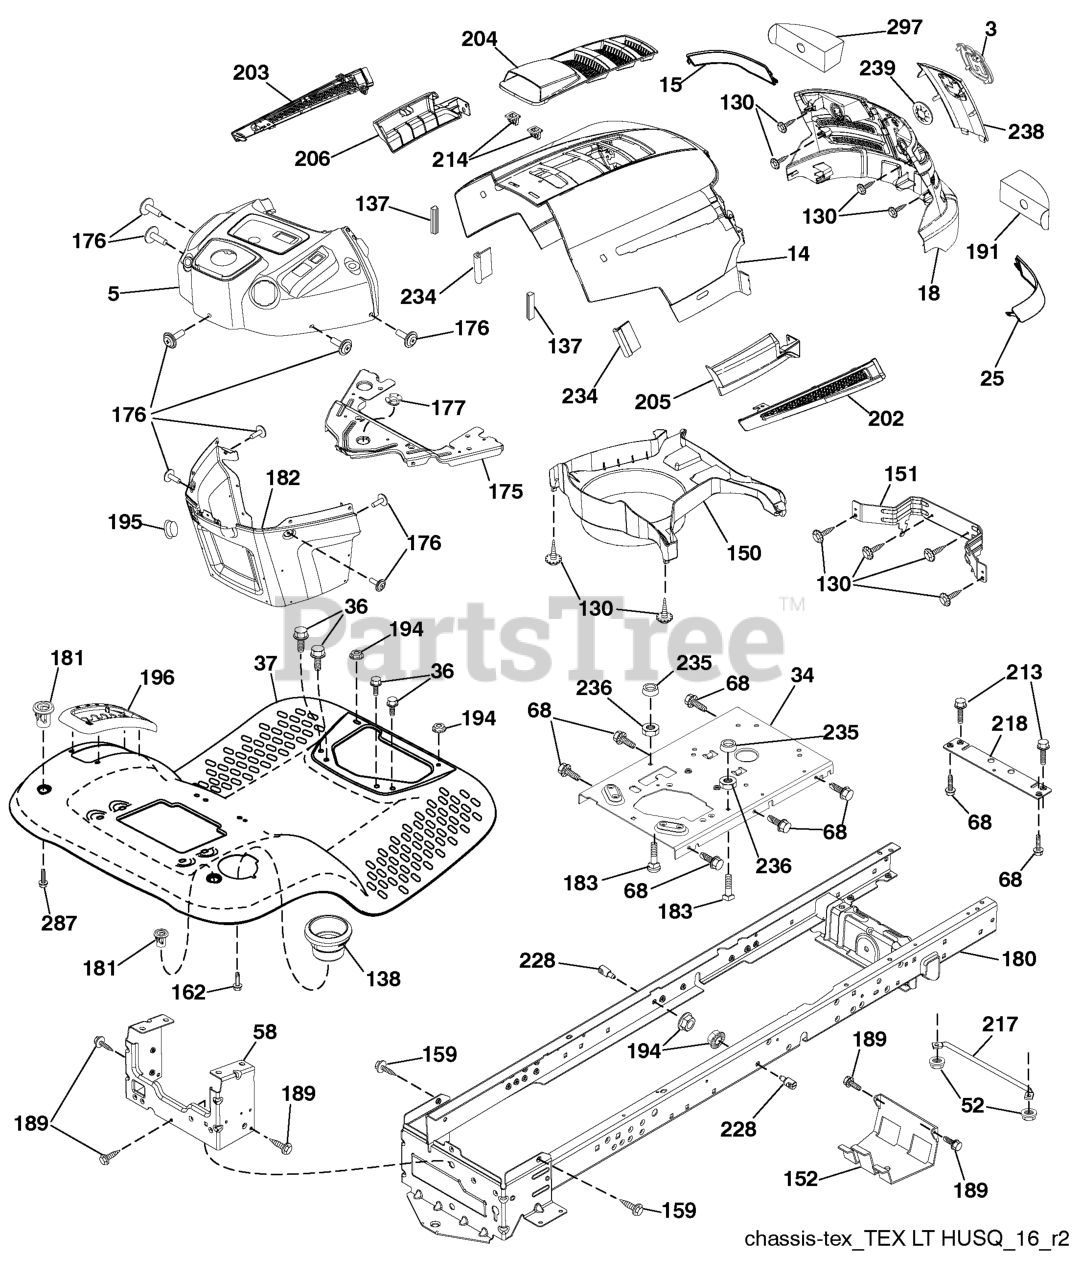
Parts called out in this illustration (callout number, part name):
3	RP LOGO
5	DASH
14	HOOD
15	LENS.HUSQVARNA LT.LH
18	GRILLE.SVC.HUSQVARNA.LT.GREY
25	LENS.HUSQVARNA LT.RH
34	PLATE.ENGINE.WELDED.CHASSIS
36	SCREW 5/16"
37	RP FENDER.TLT.FS.W/CPH.422
52	LOCKNUT
58	DRAWBAR UPPER 2PC SMALL FENDER
68	Screw THDROL 5/16-18 x 1/2
130	SCREW.#10 X 0.750.BOS
137	BUMPER DASH
138	CUPHOLDER.TL.TEX.418
151	BRACKET PIVOT
152	SHIELD.BROWNING.W/TEX
159	SCREW, 3/8-16X3/4
162	SCREW.HI-LO.CONSOLE
175	CROSSMEMBER
176	SCREW.#10-24X5/8.RN.QU
177	BUSHING STEERING
180	CHASS.WLDMNT.TL.12GA/2P.48/54
181	BUSHING.MNT.FEND.CRGO.
182	DASH.LOWER.PREDATOR LT
183	BOLT.5/16-18X1-1/4 FULL THD
189	SCREW
191	INSERT.REFLECTIVE.RH.
194	NUT LOCK HEX FLANGE 5/16-18
195	PLUG DASH
196	RP CONSOLE.ASM.DECKLFT.GR/RBT.
202	VENT SIDE HOOD LH
203	VENT SIDE HOOD RH
204	VENT TOP HOOD
205	SKIRT SIDE RH
206	SKIRT SIDE LH
213	BOLT
214	CLIP.RETAINER.TINNER.
217	ROD.PIVOT.HOOD
218	X-PIECE.HOOD.STOP.NON/
228	STUD.FASTNER.W/ANTI-ROTATE
234	BUMPER.HOOD.TEX.HUSQVARNA
235	SPACER FENDER
236	NUT.CENTERLOCK.5/16-
238	TRIM
287	SCREW 1/4X20
297	INSERT REFLECTIVE
